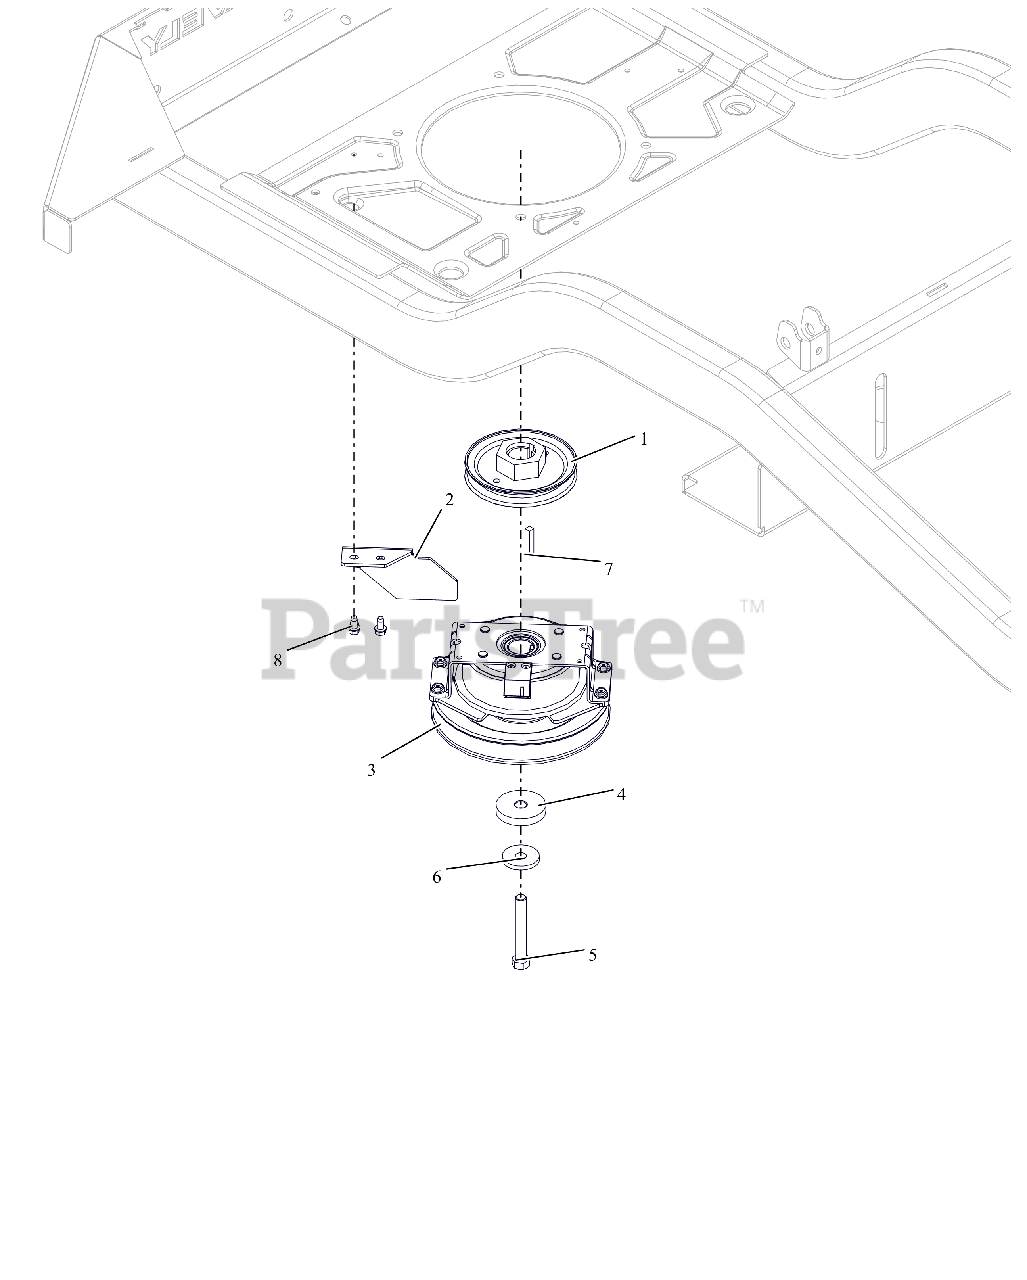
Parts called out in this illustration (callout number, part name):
1	WLDMT,PULLEY-4.50ODX1.003
2	BRKT, CLUTCH STOP HD
3	CLUTCH, OGURA DBL SPRG
4	SPACER, .474/.459X2.00X.350
5	BLT, HEX 0.4375-20X3 G8 ZCC NT
6	WASHER, 7/16" SPRING DISK
7	KEY-SQ .25 X 1.25 X .25 SAE
8	SCR-TAP .25-20X.50 HWH ZCC
